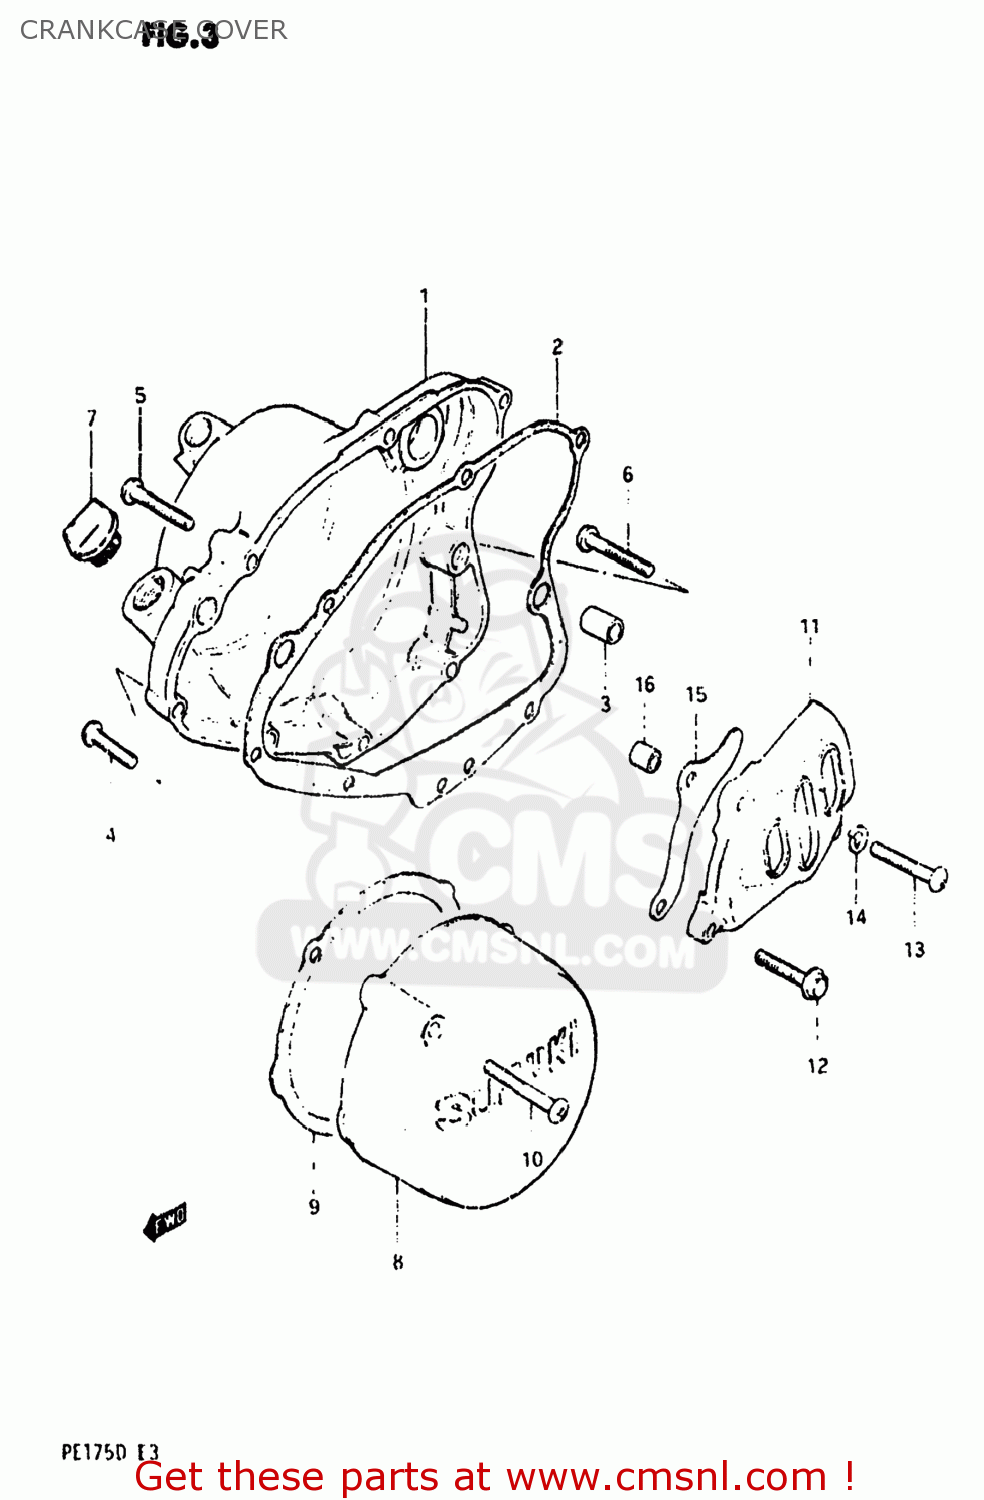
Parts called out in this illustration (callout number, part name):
1	COVER,CLUTCH
2	GASKET,CLUTCH COVER (MCA)
3	PIN
4	SCREW
5	SCREW
6	SCREW
7	PLUG,OIL FILTER
8	COVER,MAGNETO
9	GASKET,MAGNETO COVER (NAS)
10	SCREW
11	COVER,ENGINE SPROCKET
12	BOLT
13	SCREW
14	LOCK WASHER
15	PLATE,FRONT CHAIN GUIDE
16	SPACER(6.5X10.5X12)
